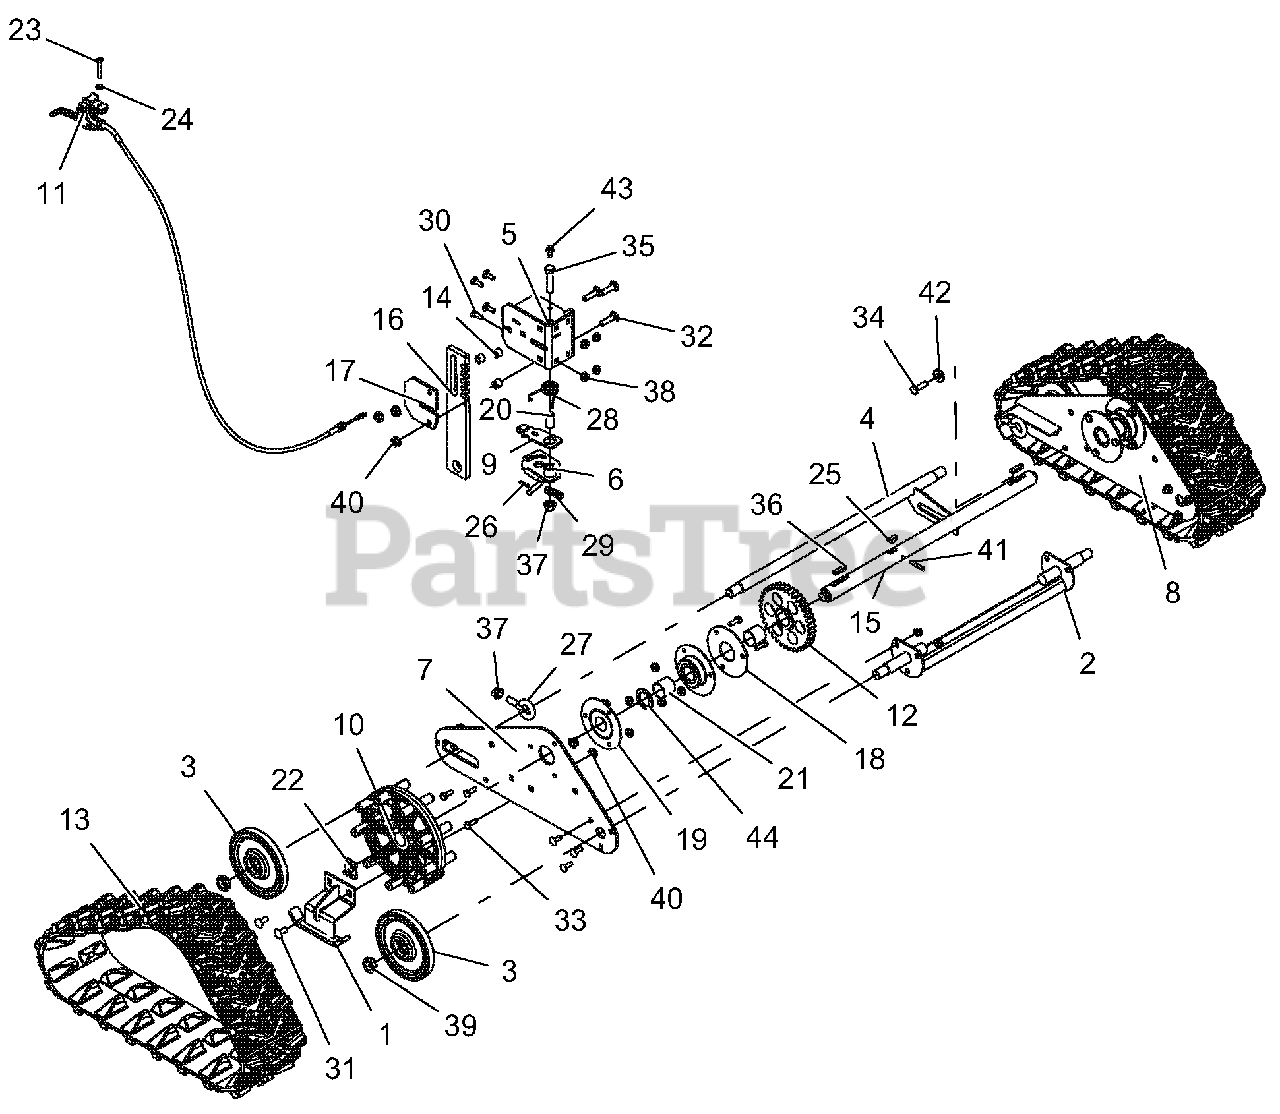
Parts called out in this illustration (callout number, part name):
1	RUNNER, GUIDE-TRACK
2	AXLE, FRONT-DELUXE TRACK
3	WHEEL, BOGIE - SINGLE BEARING
4	AXLE, REAR - DELUXE TRACK
5	BRACKET, HEIGHT ADJUSTER
6	LOCK, HEIGHT ADJUSTER
7	SIDE PLATE, RH-DELUXE TRACK
8	SIDE PLATE, LH-DELUXE TRACK
9	ARM, OVERTRAVEL
10	WHEEL, MACHINED DRIVE
11	CABLE, TRACK REMOTE
12	GEAR, SPUR
13	TRACK, RUBBER
14	SPACER .50 X .32 X .42
15	AXLE, TRACK-DELUXE
16	STOP, HEIGHT ADJUSTER - DELUXE
17	PLATE, HEIGHT ADJUSTER
18	PLATE, BEARING SPACER
19	BRG-FLG 1.003/1.000 3 BOLT
20	BSHG-SLV .385X.500X1.045
21	BSHG-SLV, 1.012X1.125X1.00
22	CLIP, SNAP .625 DIA
23	SCR-MCH .25-20X1.50 OVAL HD
24	WSHR-LK-INT .250 TH TYA
25	KEY-WDRF .25X.750X.313 SAE91
26	PIN-HAIR INT .06X.18X.77
27	BLT-EYE .375-16X.880 YWZC
28	SG-TORS .067X.88
29	SPRING-EXT .047 X .438 X 1.85
30	@BLT-RDHDSQNK .25-20X.75 G5YZ
31	@BLT-RDHDSQNK .31-18X.75 G5YZ
32	@BLT-RHDSHSQNK.31-18X1.25 G5YZ
33	@BLT-HEX .25-20X.75 GR5 YWZC
34	@BLT-HEX .31-18X1.00 GR5 YWZC
35	@BLT-HEX .38-16X1.75 GR5 YWZC
36	KEY-RECT .25X.188X1.00
37	NUT-LK-CTR-FLG .38-16 YWZC
38	@NUT-LK-CTR-FLG .25-20 YWZC
39	@NUT-LK-NYL .625-18 YWZC
40	@NUT-LK-TOP-FLG .31-18 YWZC
41	PIN-ROLL .188X1.25
42	BSHG-FLG .325X.499X.3X.875
43	SCR-TAP .25-20X.50 HWH TR YWZ
44	WSHR-FL-STL 1.010X1.505X.062YZ
